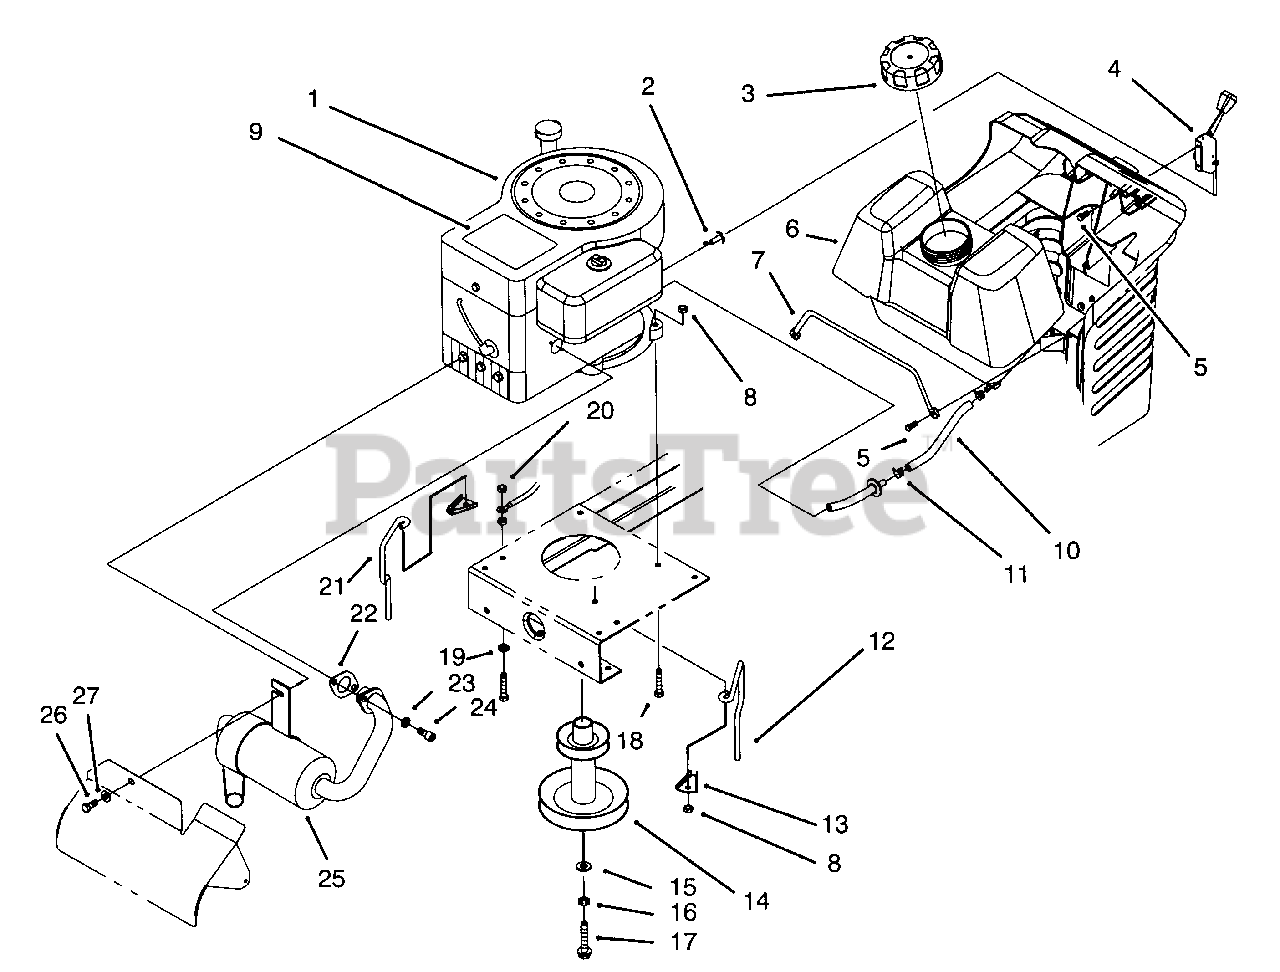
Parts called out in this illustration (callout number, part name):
1	Engine-12.5 H.P. (Model No. 81180 Only)
2	Cable-Throttle
4	Control-Throttle
5	Screw-Plastite
6	Tank-Gas
7	Rod-Gas Tank
8	Nut-Lock
9	Decal-Engine 12.5 (Model No. 81180 Only)
10	Line-Fuel
11	Clamp-Hose
12	Guide-Belt L.H.
13	Anchor-Belt Guide
14	Pulley-Engine
15	Washer-Flat
16	Washer-Lock
17	Bolt-Blade
18	Screw-Hex Hd. Cap
19	Washer-Ext. Tooth Lock
20	Nut-Keps
21	Guide-Belt R.H.
22	Gasket-Muffler
23	Washer-Lock
24	Screw-Hex Soc. Hd.
26	Screw-Hex Hd. Cap
27	Washer-Lock
